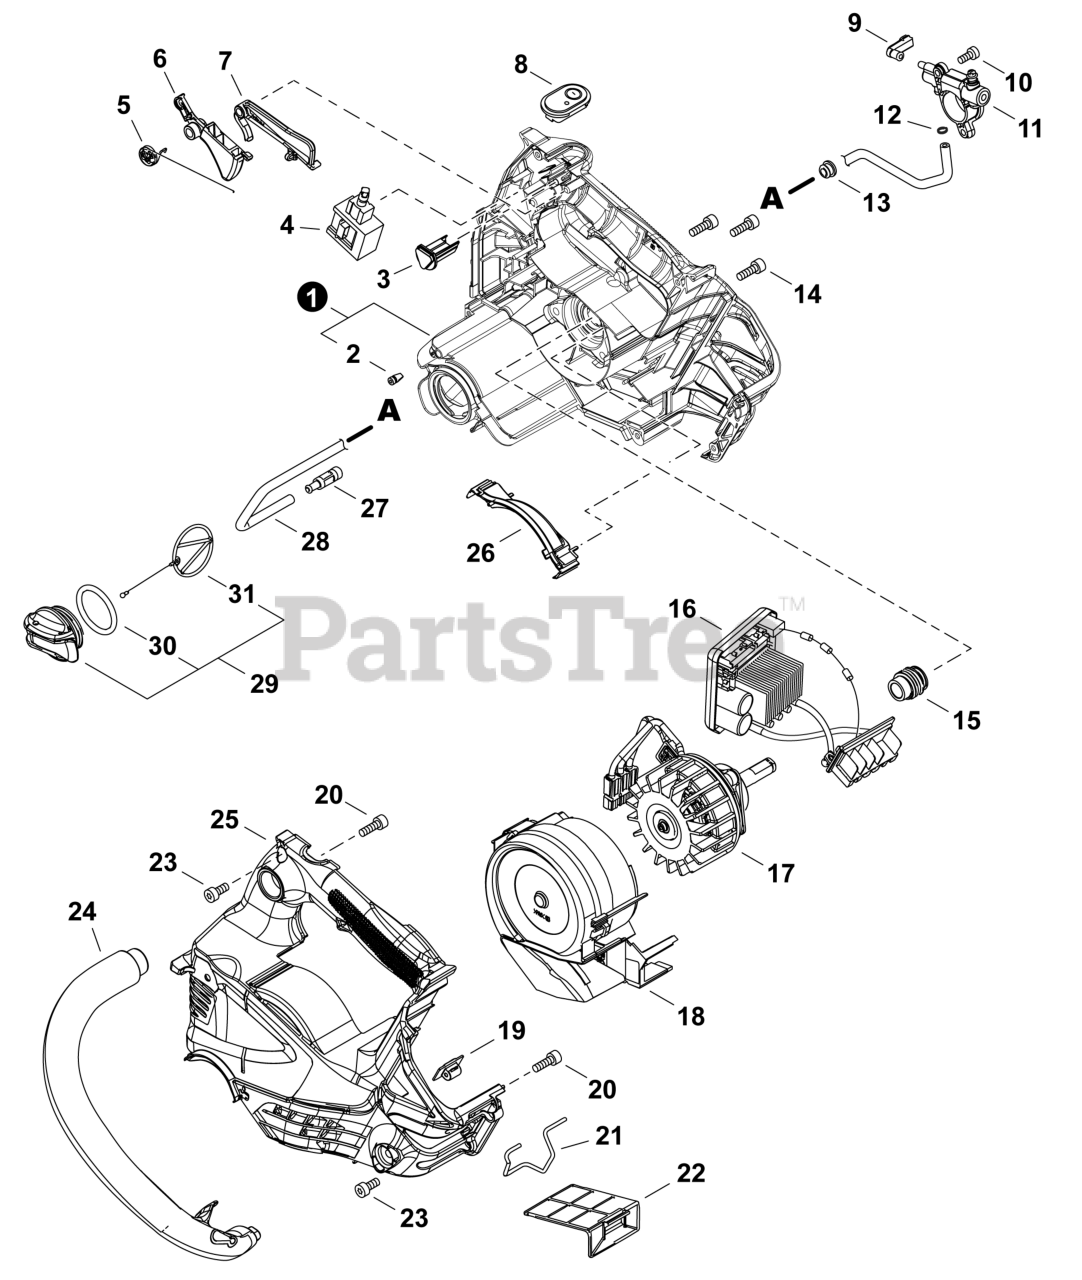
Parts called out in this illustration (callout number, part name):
1	HOUSING ASSY, MOTOR
2	VENT ASSY
4	SWITCH, SPEED CONTROL
5	SPRING, TORSION
6	TRIGGER
7	LOCKOUT, TRIGGER
8	SWITCH, ON-OFF
9	PIPE, OIL
10	BOLT, TORX 4x12
11	AUTO-OILER ASSY
12	CLIP 6.5 MM
14	BOLT, TORX 5x16
15	GEAR, WORM
16	CONTROL BOARD ASSY
17	MOTOR ASSY
18	CASE ASSY, FAN
19	BRACKET, HARNESS
20	BOLT, TORX 5x16
21	RING, HARNESS
22	FILTER, AIR
23	BOLT, TORX 4x12
24	HANDLE, FRONT
25	COVER, MOTOR
26	COVER, MOTOR
27	FILTER ASSY, OIL
28	PIPE, OIL 3x6x200
29	CAP ASSY, OIL
30	O-RING 29
31	CONNECTOR, CAP L= 60 MM
